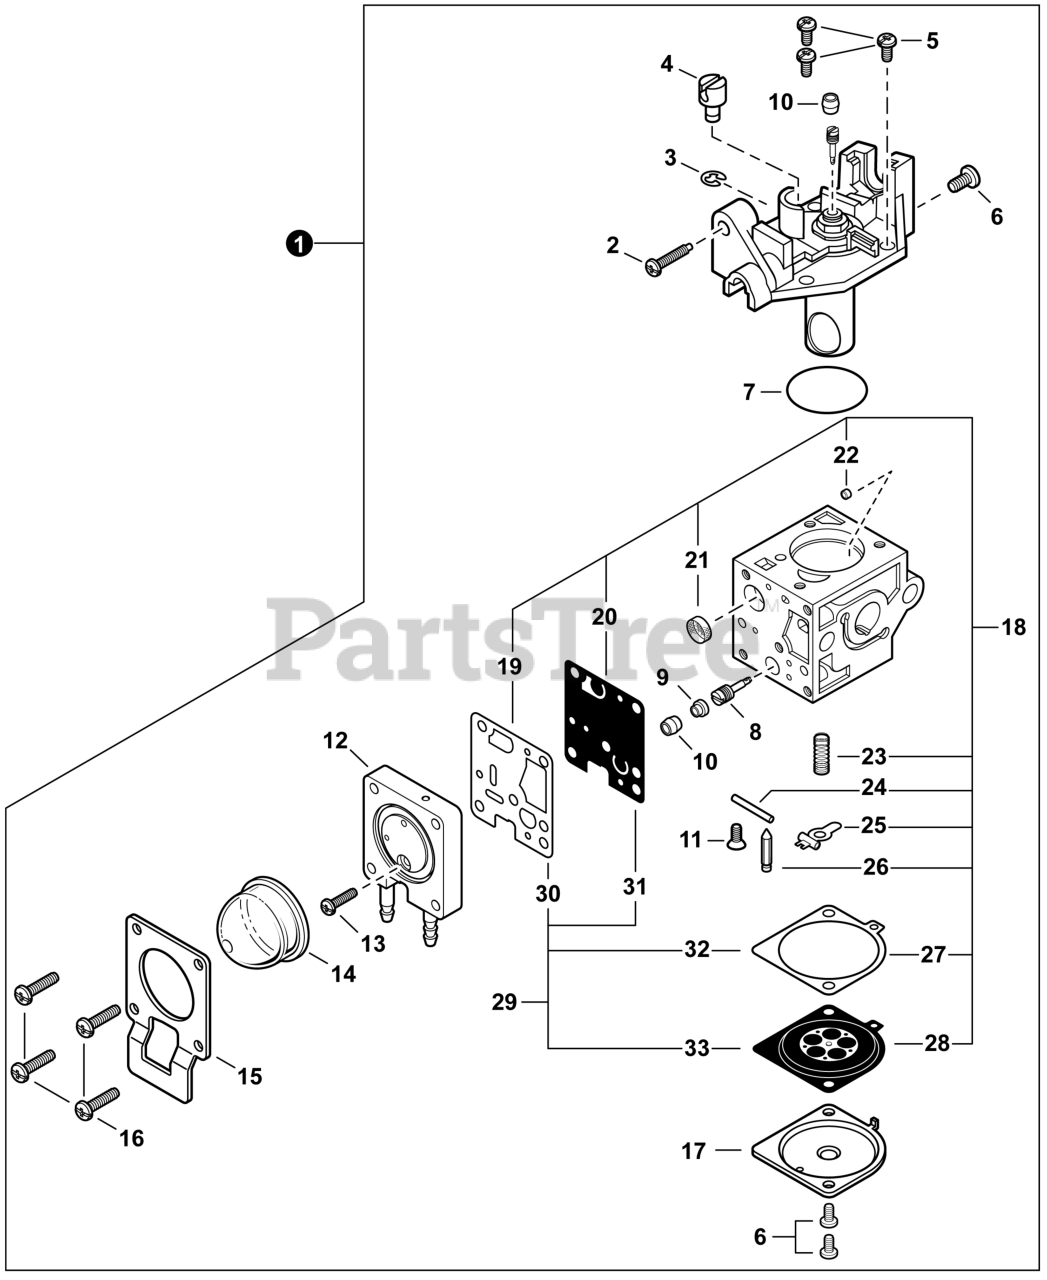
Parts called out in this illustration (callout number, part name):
1	CARBURETOR - Z011-0GA
2	SCREW, IDLE ADJUST
8	NEEDLE, HIGH SPEED
9	CAP, LIMITER
12	BODY ASSY, PURGE
14	BULB, PURGE
15	RETAINER, PURGE BULB
17	COVER, METERING DIAPHRAGM
18	REPAIR KIT, CARBURETOR
19	GASKET, PUMP
20	DIAPHRAGM, PUMP
21	SCREEN, FUEL INLET
22	GUIDE, ROLLER
23	SPRING, METERING LEVER
24	PIN, METERING LEVER
25	LEVER, METERING
26	VALVE, INLET NEEDLE
27	GASKET, METERING DIAPHRAGM
28	DIAPHRAGM, METERING
29	GASKET / DIAPHRAGM KIT
30	GASKET, PUMP
31	DIAPHRAGM, PUMP
32	GASKET, METERING DIAPHRAGM
33	DIAPHRAGM, METERING
